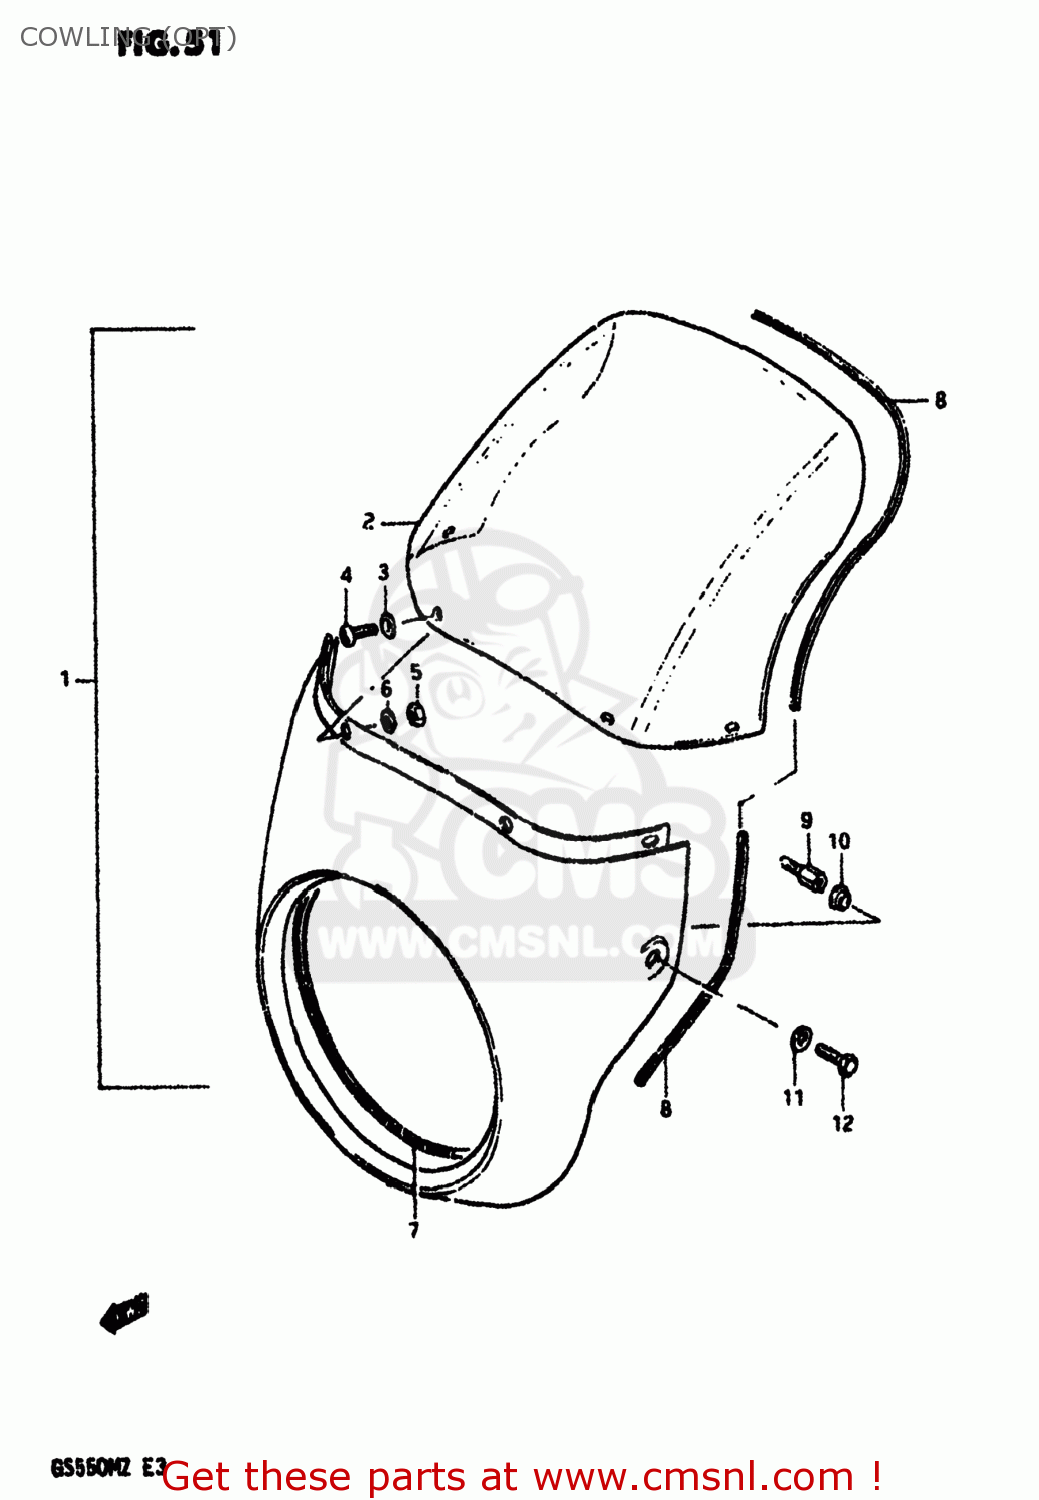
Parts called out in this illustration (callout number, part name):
1	COWLING ASSEMBLY,BODY
2	WINDSCREEN
3	CUSHION
4	SCREW
5	NUT
6	WASHER
7	MOLDING,COWLING
8	MOLDING
9	HOUSING,HEADLAMP
10	WASHER
11	WASHER(6.5X16X1.2)
12	BOLT
